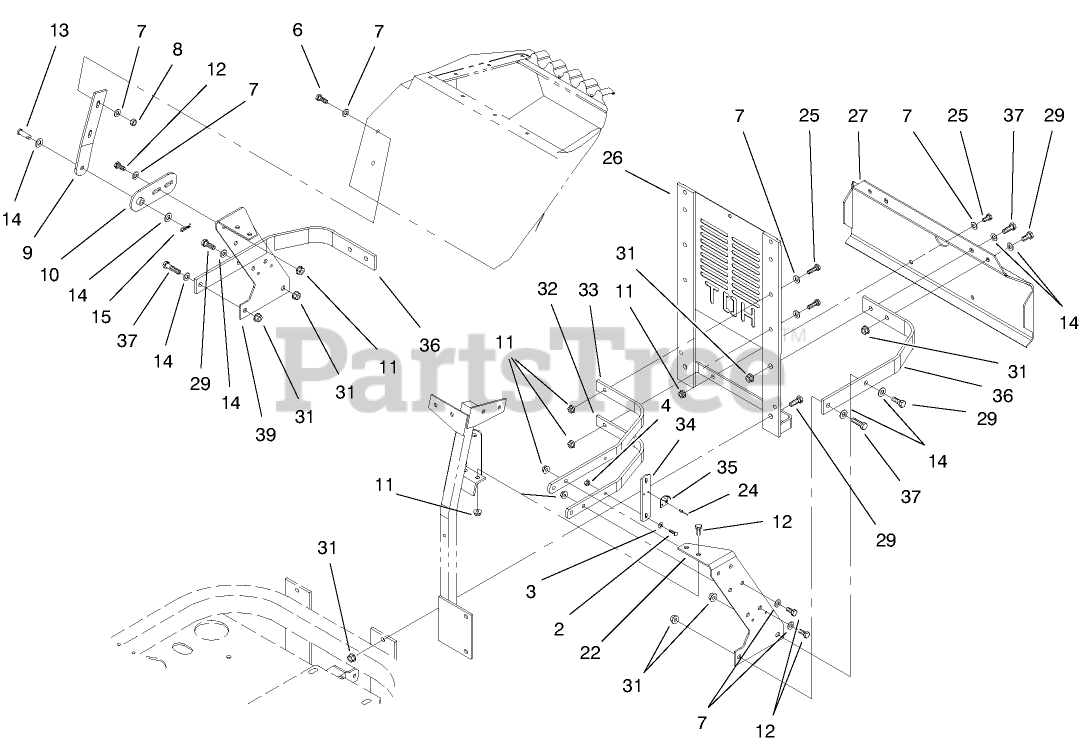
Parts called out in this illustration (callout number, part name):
2	Screw-HSBH
3	WASHER-FLAT
4	Nut
6	SCREW-HH
7	WASHER-PLAIN
8	NUT-LOCK NI
9	Plate-Hinge, Hood
10	Shackle Hinge ASM
11	NUT-HF
12	SCREW-HH
13	Pin-Clevis
14	WASHER-FLAT
15	Pin-Hair Cotter
22	Plate-Mount, Radiator
24	Rivet
25	SCREW-HH
26	Rear Radiator Mount ASM
27	Bumper-Rear
29	SCREW-HH
31	NUT-HHF, WHIZ
32	Rib-Top
33	Rib-Bottom
34	Bar-Hook, Latch
35	Keeper-Latch, Rubber
36	Bar-Frame, Radiator Mount
37	SCREW-HH
39	Plate-Mount, Radiator
